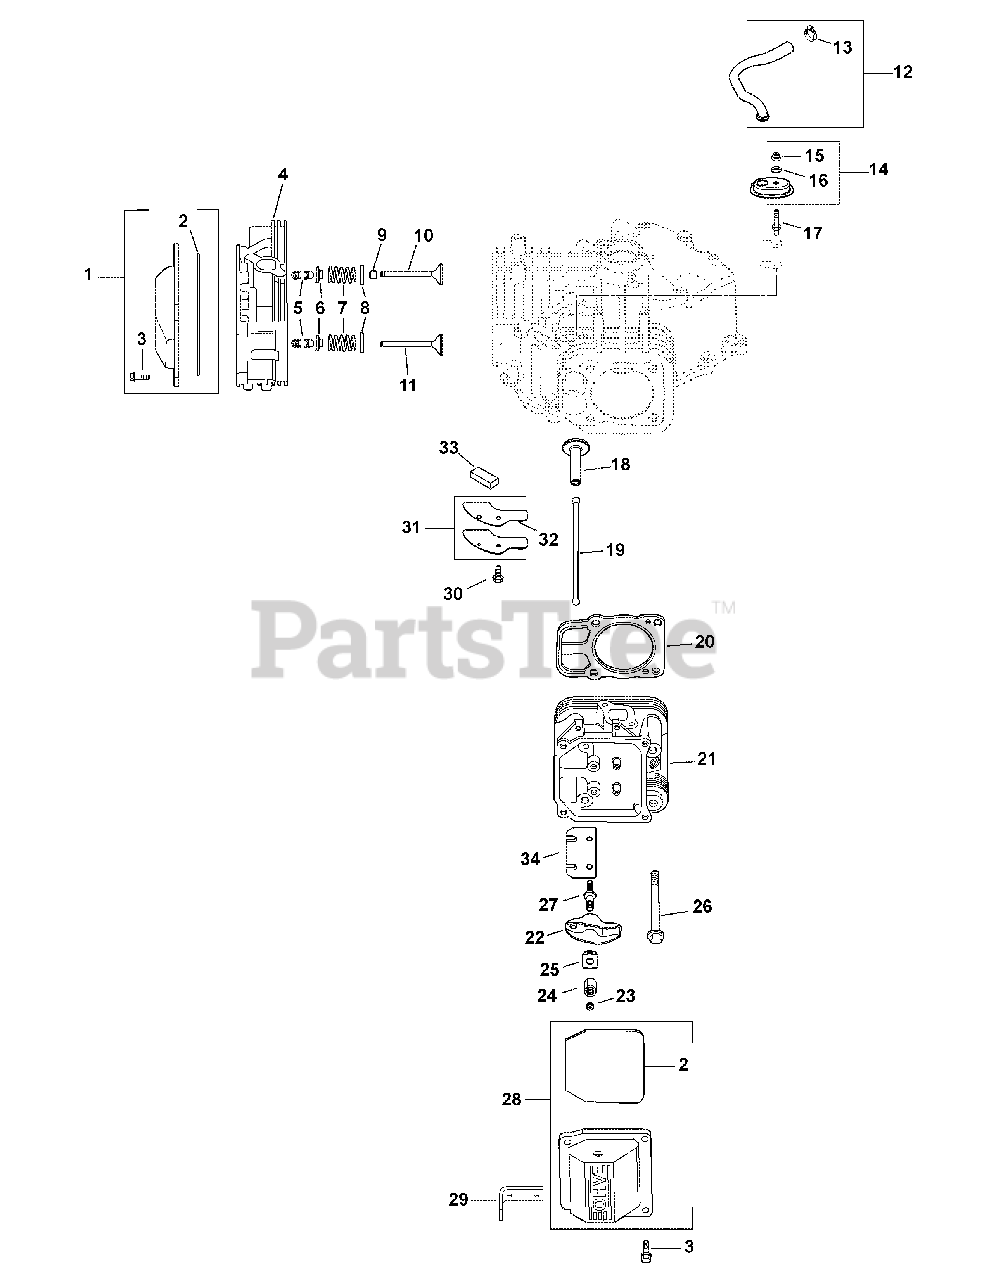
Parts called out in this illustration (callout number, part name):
1	Kit, Rocker Cover
2	O-Ring, Valve Cover
3	Screw, Flnge M6 x 1.0 x 30
4	Kit, #1 Cylinder Head
5	Kit, Retainer
6	Cap, Valve Spring
7	Spring, Valve
8	Retainer, Spring
9	Seal, Valve Stem
10	Valve, Intake (Std.)
11	Valve, Exhaust (Std.)
12	Kit, Breather Hose,
13	Clamp, Hose
14	Kit, Breather Housing
15	Nut, Lock, M5 x 0.8
16	Washer, Sealing
17	Stud, Breather Cover
20	Kit, Cylinder Head Gasket
21	Kit, #2 Cylindre Head
23	Nut, M10 x 0.75
24	Screw, Set
25	Pivot, Rocker Arm
26	Screw, Flange, M10 x 1.5 x 90
28	Kit, Breather Valve Cover
29	Strap, Lifting
30	Screw, Flnge Thrd. Frmng M6 x 1.0 x 16
31	Kit, Breather Cover
32	Gasket, Breather Cover
33	Filter, Breather
